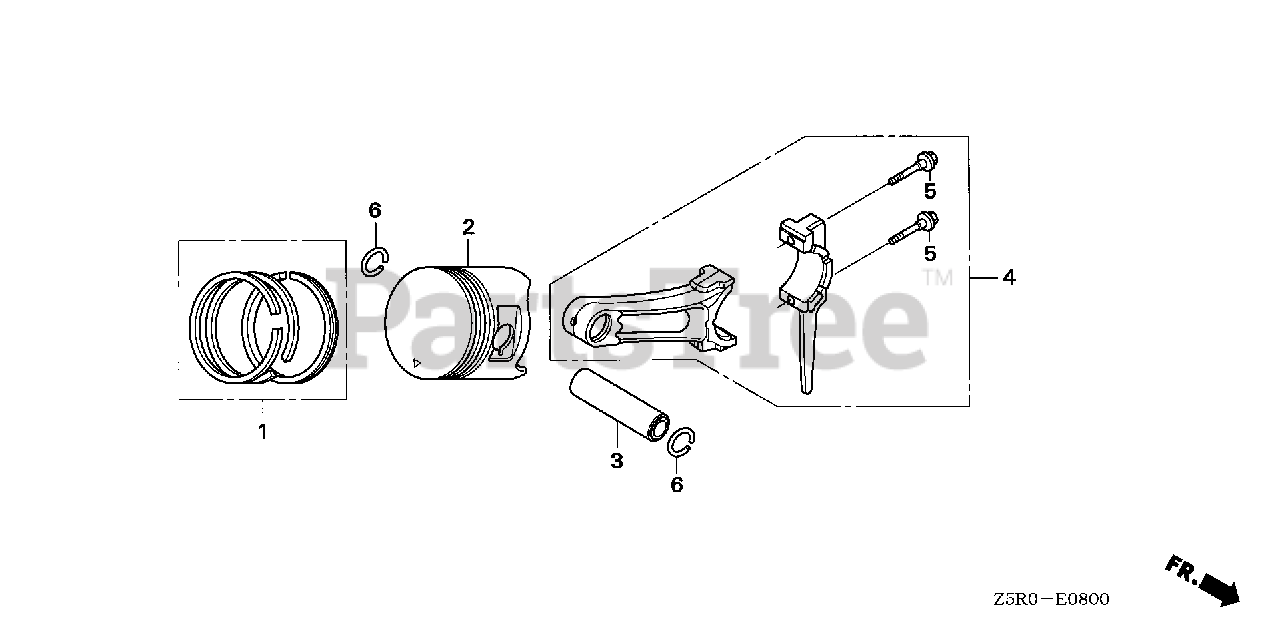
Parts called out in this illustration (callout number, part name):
1	RING SET, PISTON (STD) (TEIKOKU)
1	RING SET, PISTON (0.25) (TEIKOKU)
1	RING SET, PISTON (0.50) (TEIKOKU)
1	RING SET, PISTON (0.75) (TEIKOKU)
2	PISTON (STD)
2	PISTON (0.25)
2	PISTON (0.50)
2	PISTON (0.75)
3	PIN, PISTON
4	ROD ASSY., CONNECTING (STD.)
4	ROD ASSY., CONNECTING (0.25 LOWER SIZE)
5	BOLT, CONNECTING ROD
6	CLIP, PISTON PIN (20MM)
